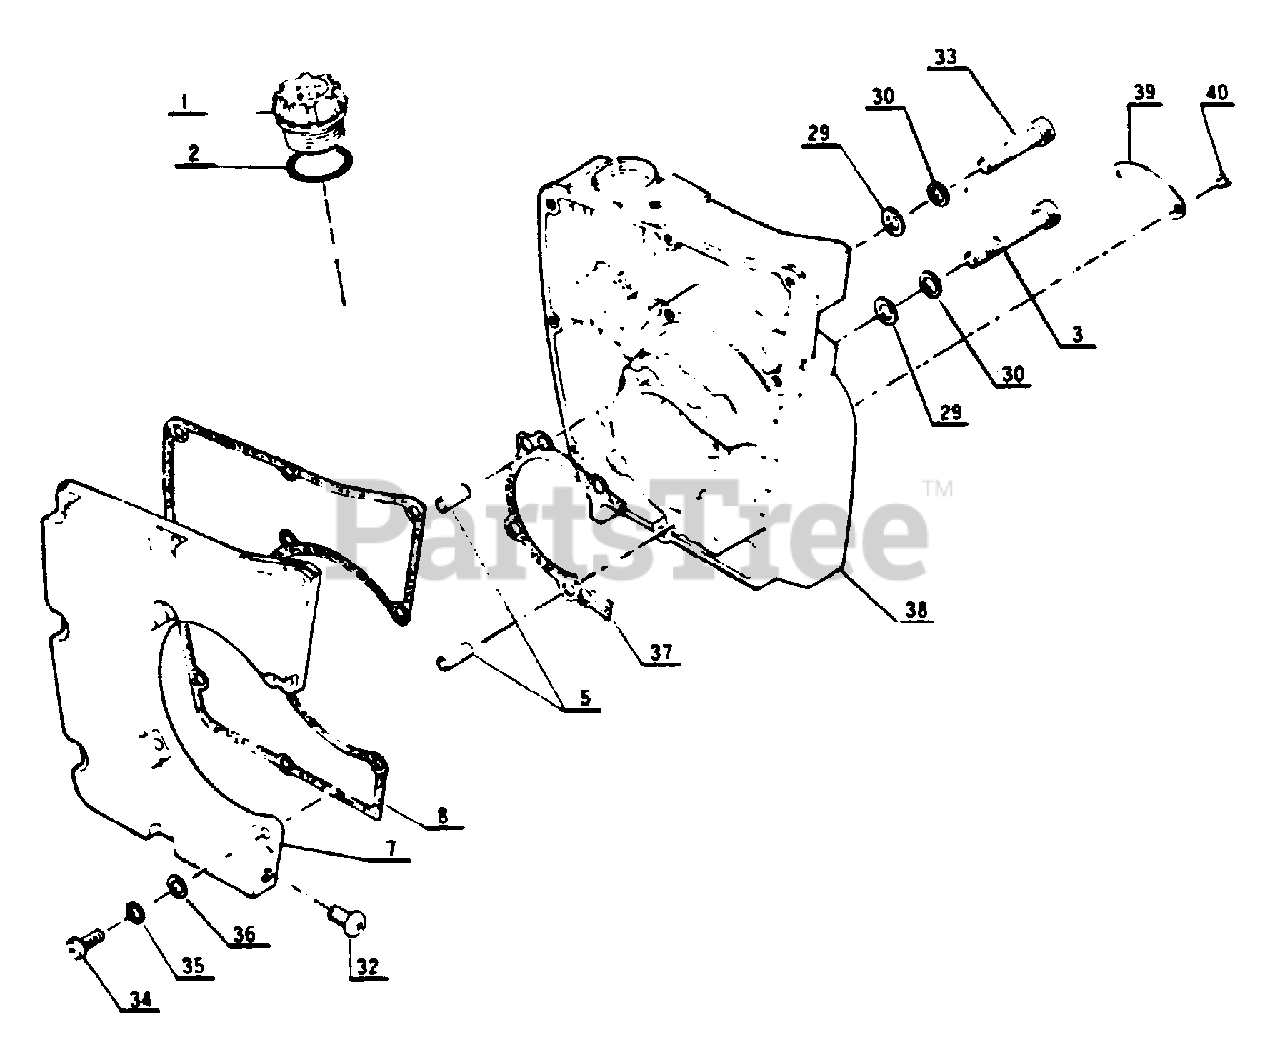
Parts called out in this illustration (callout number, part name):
1	CAP
2	GASKET, CAP
3	BOLT
5	PIN, LOCATING 5×10
7	TANK, OIL
8	OIL TANK PACKING
29	WASHER
30	WASHER, SPRING 5
32	SCREW - 4×8
33	BOLT
34	SCREW - 4×12
35	WASHER, SPRING 4 MM
36	WASHER 4 MM
37	GASKET, CRANKCASE
38	CRANKCASE
39	MODEL PLATE
40	RIVET
